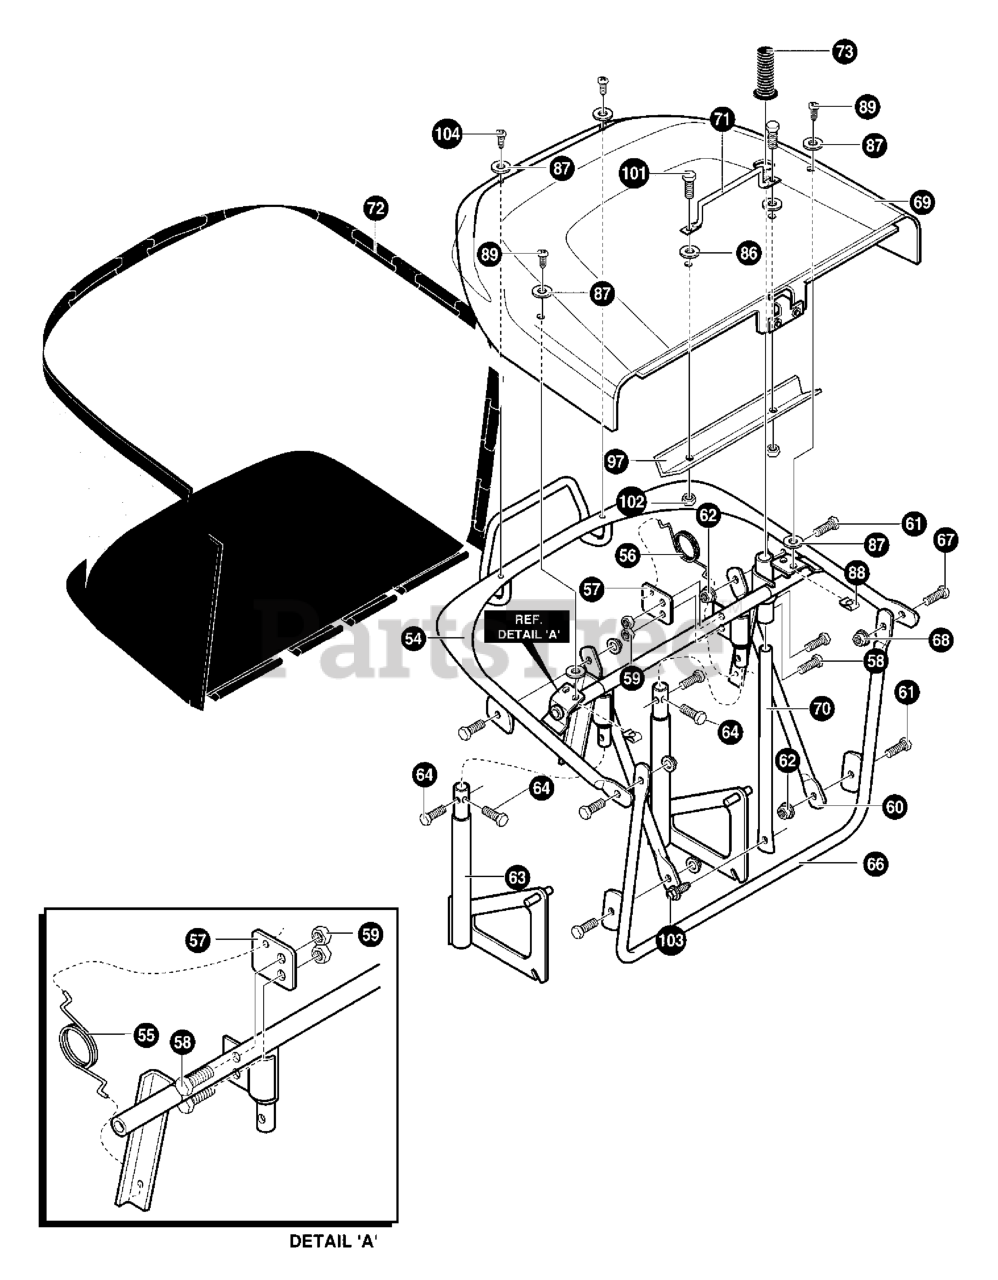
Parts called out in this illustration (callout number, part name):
54	ASM. WLD- UPPER FRAME
55	SPRING, TORSION RH BAG CLOSE
56	SPRING, TORSION LH BAG CLOSE
57	BRACKET, SPRING COLLECTOR
58	SCREW, 1/4-20X.50
59	NUT, 1/4-20 REGHEXCTRLK
60	BRACE, FRAME COLLECTOR
61	SCREW, 1/4-20X.62
62	NUT, 1/4-20 HEXNYL
63	ASM. SUPPORT COLLECTOR
64	SCREW, 5/16-18 x 1.50
66	ASM., FRONT FRAME COLLECT
67	SCREW, 1/4-20X.62
68	NUT, 1/4-20 HEXNYL
69	TOP COLLECTOR ASM.
70	HANDLE, DUMP REBA COLLECTOR
71	HANDLE, REBA COLLECTOR
72	REBA COLLECTOR BAG
73	RUBBER GRIP
85	NUT, 5/16-18WDFLLK
86	WASHER, .281X1.25X.06
87	WASHER, FLAT .328X1.06X.062
88	NUT, 1/4-20 TINN U
89	SCREW, 1/4-20X.63 PHPNHD
97	BRACE, BAGGER
101	SCREW, 1/4-20X1.50 SLHWATAP
102	NUT, 1/4-20 HEXNYL
103	SCREW, #12X.50 PHPNHTAP
104	SCREW, #12X.50 PHPNHTAP
